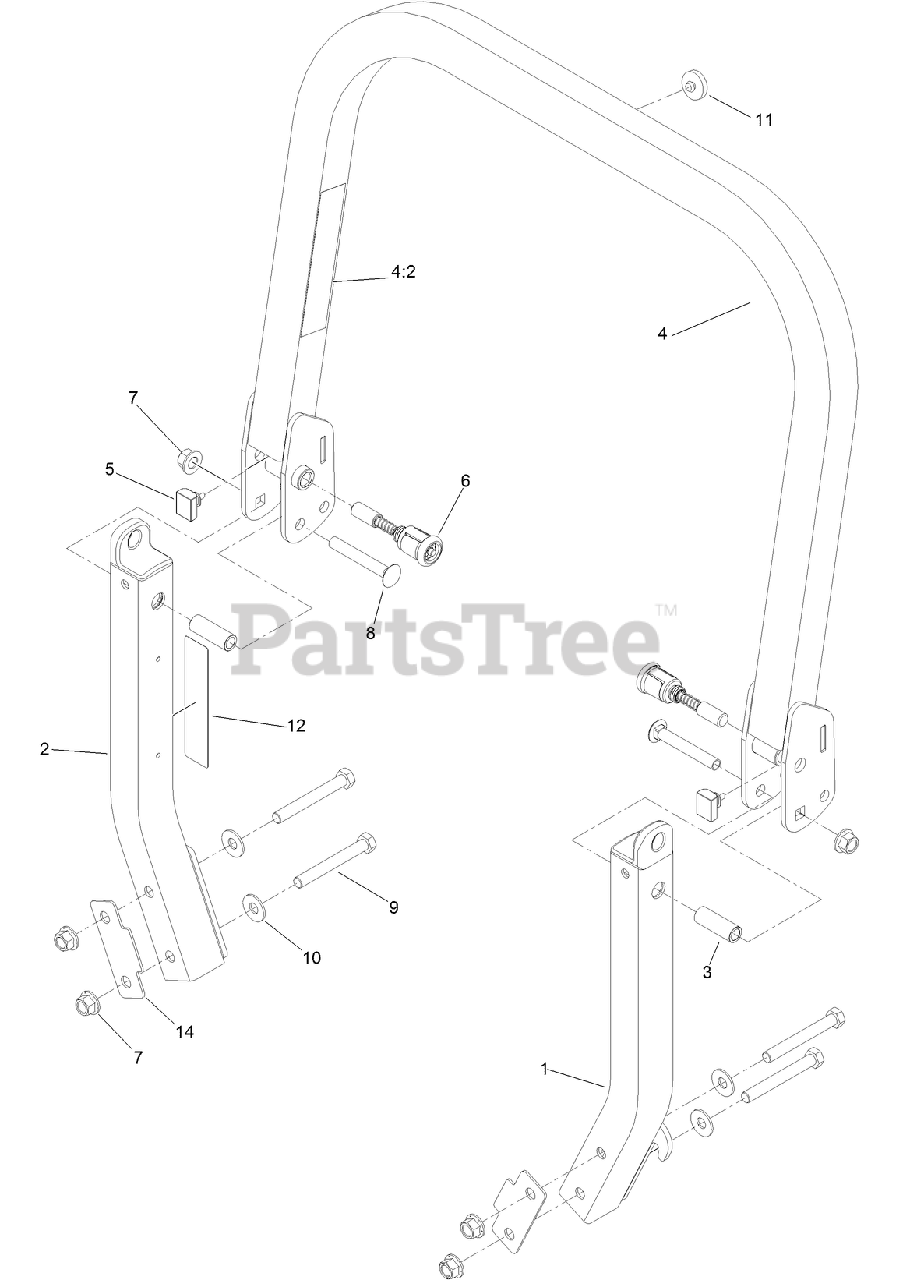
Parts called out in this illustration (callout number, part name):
1	LEG-ROPS, LH
2	LEG-ROPS, RH
3	SPACER
4	UPPER ROPS ASM
4:2	DECAL-WARNING
5	BUMPER-ROPS
6	PIN-SPRING
7	NUT-LOCK
8	SCREW-CARR
9	SCREW-HH
10	WASHER-SPRING
11	BUMPER-PUSH-IN, RUBBER
12	DECAL-CAUTION, FUEL VENT
14	SPACER
